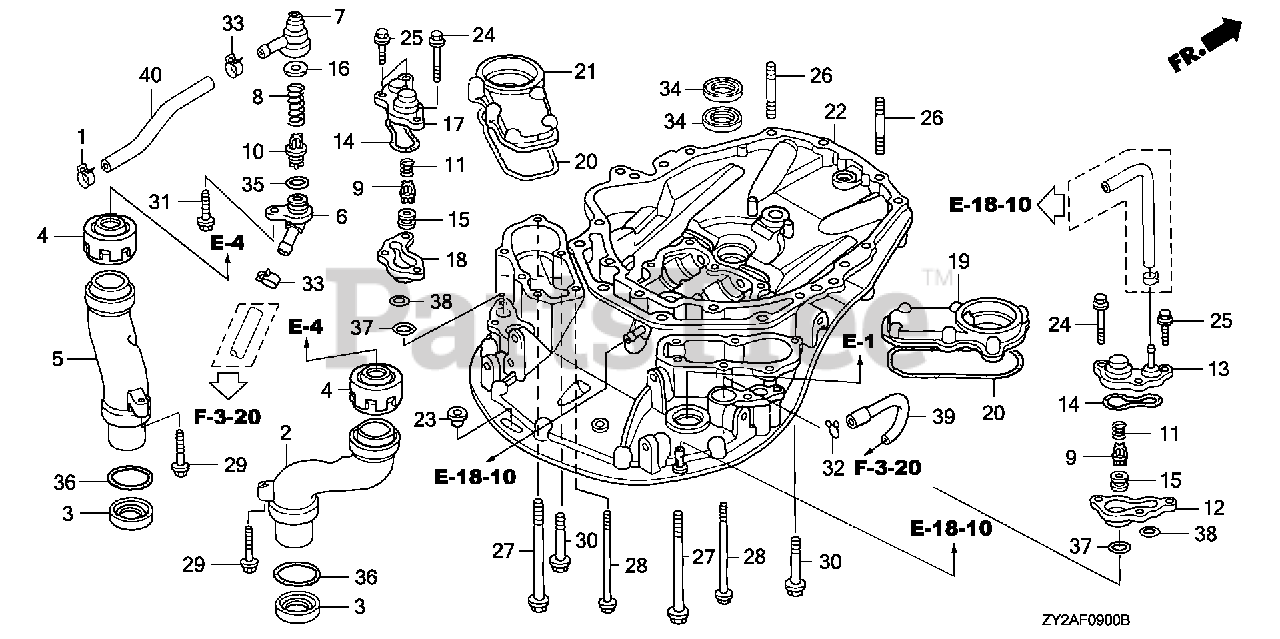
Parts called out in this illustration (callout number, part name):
1	CLIP, TUBE
2	GUIDE, R. EX. *TGRAY* (GRAY)
3	SEAL, EX. GUIDE
4	SEAL B, EX. GUIDE
5	GUIDE, L. EX. *TGRAY* (GRAY)
6	COVER, FLUSH VALVE *NH8* (DARK GRAY)
7	CASE, FLUSH VALVE
8	SPRING, FLUSH VALVE
9	VALVE, RELIEF
10	VALVE, FLASH
11	SPRING, RELIEF VALVE
12	SPACER, R. RELIEF VALVE *TGRAY* (GRAY)
13	COVER, R. RELIEF VALVE
14	GASKET, RELIEF VALVE COVER
15	GASKET, RELIEF VALVE
16	GASKET, FLASH VALVE
17	COVER, L. RELIEF VALVE
18	SPACER, L. RELIEF VALVE *TGRAY* (GRAY)
19	COVER, R. WATER JACKET *NH8* (DARK GRAY) (NOT AVAILABLE)
20	GASKET, WATER JACKET COVER
21	COVER, L. WATER JACKET *NH8* (DARK GRAY)
22	CASE, MOUNT *NH8* (DARK GRAY)
23	RUBBER, MOUNT CASE SEAL
24	BOLT, FLANGE (6X22)
25	BOLT, FLANGE (6X32)
26	BOLT, STUD (10X45)
27	BOLT, FLANGE (8X100)
28	BOLT-WASHER (6X121)
29	BOLT, FLANGE (6X40)
30	BOLT, FLANGE (8X30)
31	BOLT-WASHER (6X29)
32	CLIP, TUBE (B10)
33	CLIP, TUBE (B12.5)
34	SEAL, WATER (22X35X7)
35	O-RING (16MM)
36	O-RING (49.4X3.1)
37	O-RING (33.5X2)
38	O-RING (23.5X2)
39	TUBE, WATER CHECK
40	TUBE, FLUSH VALVE
